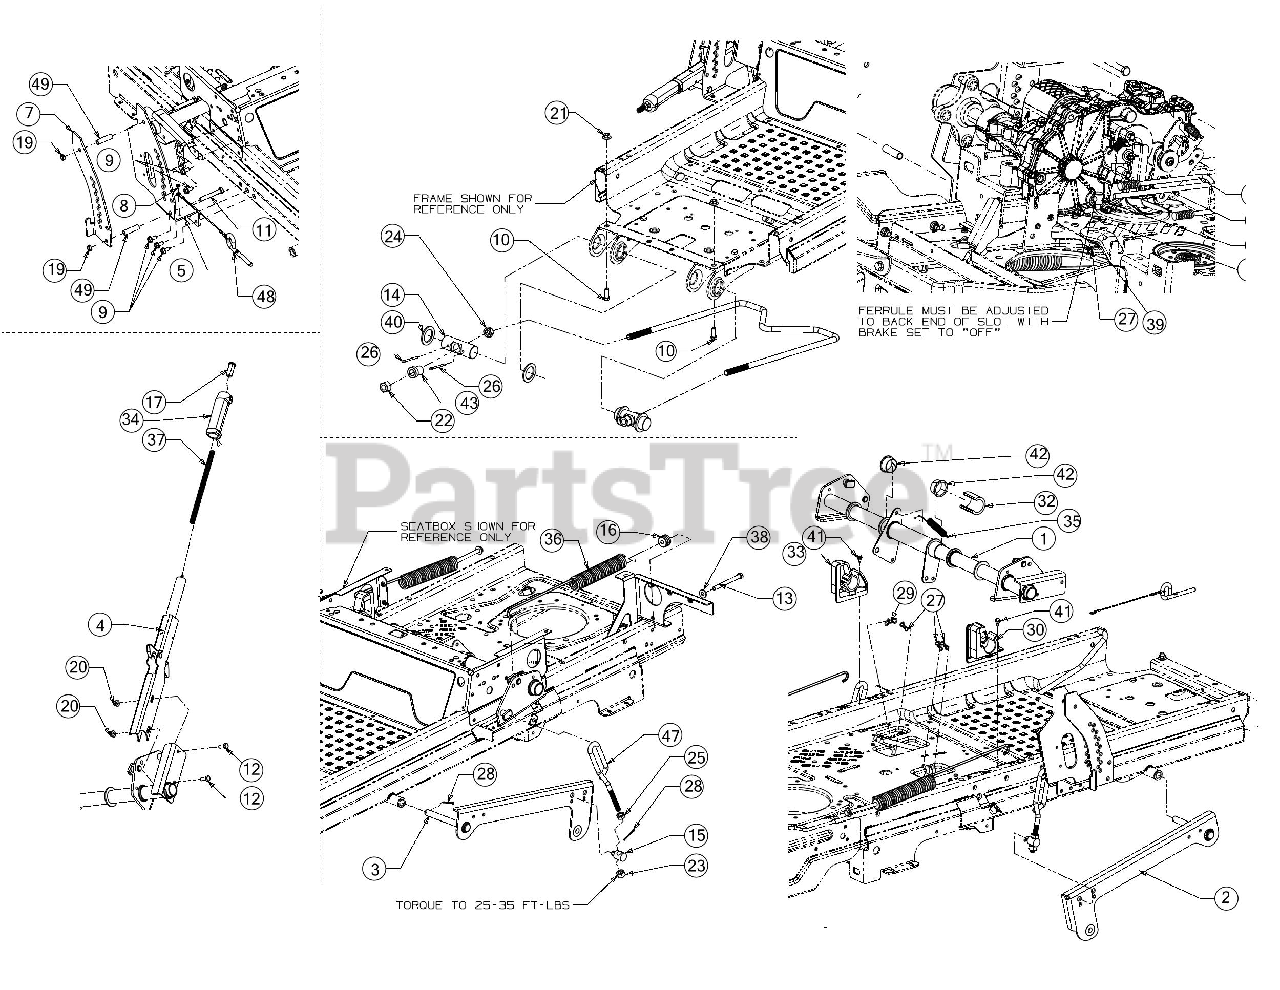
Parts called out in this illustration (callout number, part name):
1	DECK LIFT SHAFT ASSEMBLY
4	LATCH HANDLE ASSEMBLY
6	BRAKE ROD ASSEMBLY
8	HEX SCREW AB-TAP #10-16 X 0.500
9	SCREW 5/16-18 X .750
10	SCREW 3/8-16 X 1 GR5
11	HEX SCREW-3/8-16X2.5 GR5
12	SCREW 5/16-18 X .75 GR5
13	SCREW 3/8-16X4.25 GR5
15	LIFT LINK FERRULE
16	SPRING INSERT
17	LIFT HANDLE BUTTON
18	FERRULE 3/8-24 X .375
19	JAM LOCK NUT
20	FLANGE LOCK NUT 5/16-18
21	FLANGE LOCK NUT
23	HEX NUT NYLOK 1/2-13
24	HEX NUT
25	HEX NUT
26	COTTER PIN
27	BOW TIE COTTER PIN 1/4-5/16
28	COTTER PIN
29	BOW TIE COTTER PIN
31	DECK LIFT BRACKET
32	SPACER-1.375 SHAFT
33	DECK LIFT BRACKET (LH)
34	LIFT HANDLE GRIP
35	EXTENSION SPRING .63 X 4.95
36	EXTENSION SPRING
37	COMPRESSION SPRING
38	FLAT WASHER .385X.870X.090
39	WASHER THRUST .375X.70X.030
40	FLAT WASHER
41	SHOULDER SCREW 1/4-20X.50 19PSH"
42	FLANGE BEARING
43	FLANGE BEARING
45	DISENGAGEMENT BRAKE ROD
46	DECK FRONT HANGER ROD
47	LIFT ADJUSTMENT LINK
